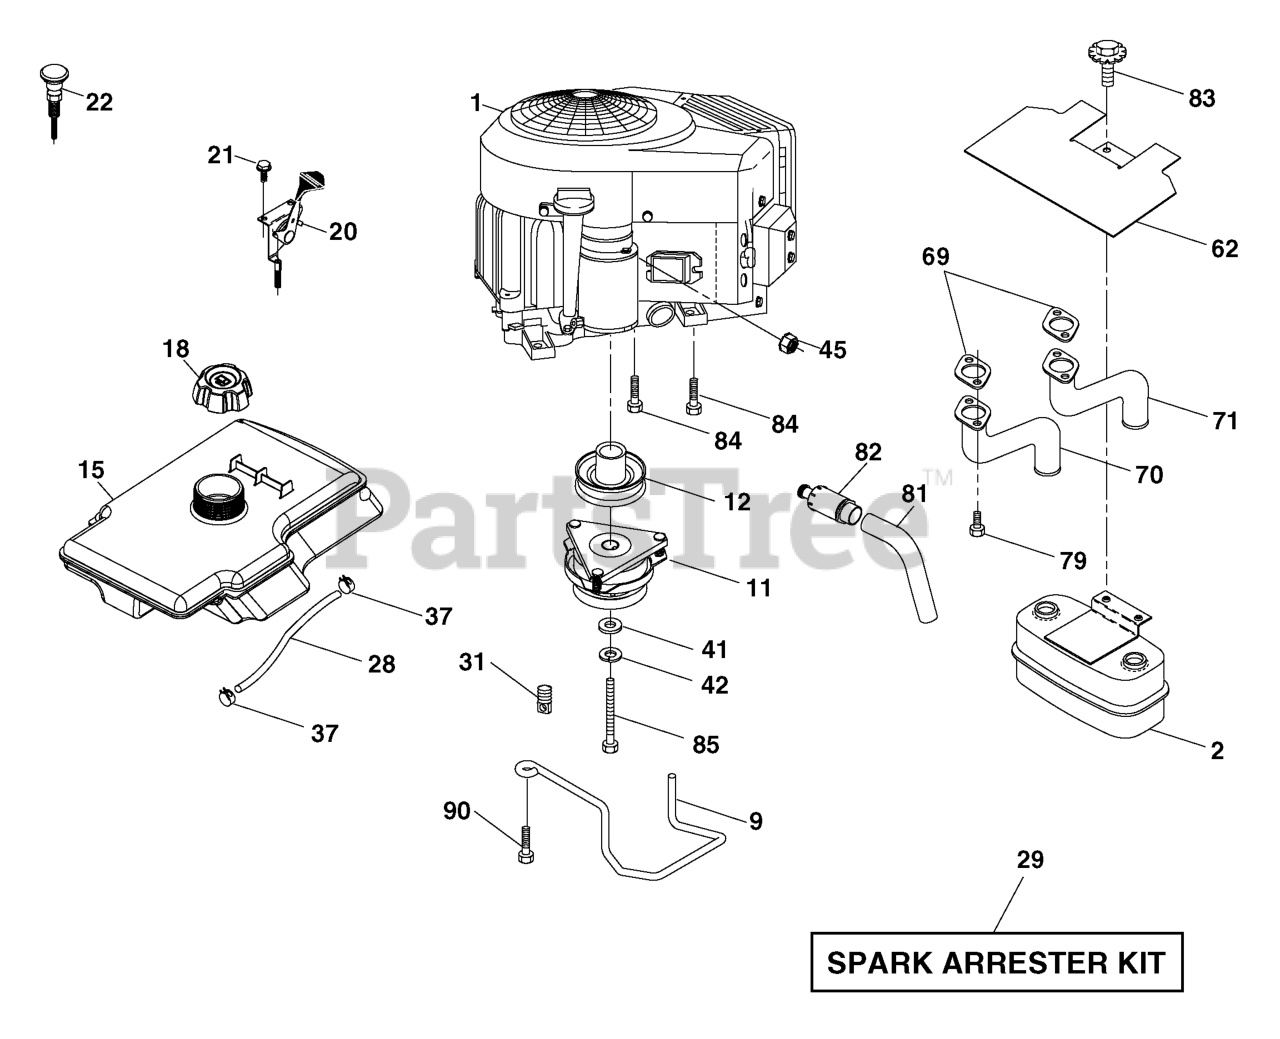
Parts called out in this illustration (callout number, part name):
2	MUFFLER.TWIN.CYL.LOW.TONE
9	KEEPER.BELT.ENGINE.3.25 (3 2)
11	RB.CLUTCH.OGURA.4.4.PD
12	PULLEY.ASM.ENG.OGURA.3
15	TANK.FUEL.2.5.RR.MNT.H
18	CAP.ASM.FUEL.TANK.3"BL
20	THROTTLE CABLE
21	SCREW
22	CONTROL.CHOKE.ERGO.PUSH-IN.BLA
28	LINE.FUEL.64"REAR.EMIS
29	KIT.SPARK ARRESTOR 794945 B&S
37	HOSE CLAMP
42	LOCKWASHER
45	NUT
62	RP SHIELD HEAT MUFFLER
69	GASKET.MUFFLER
70	RP.EXHAUST.TUBE.LH.BS/TWIN
71	EXHAUST.TUBE.RH.BS/TWIN
79	SCREW.SOCKET.HEAD.5/16-18
81	TUBE, DRAIN OIL ASM.
82	PLUG DRAIN OIL EASY
83	BOLT.5/16-18UNCX1.W/SEMS.BLK
84	SCREW.3/8-16
85	BOLT HEX 7/16-20X4-1/4"
90	SCREW 3/8-16X1
